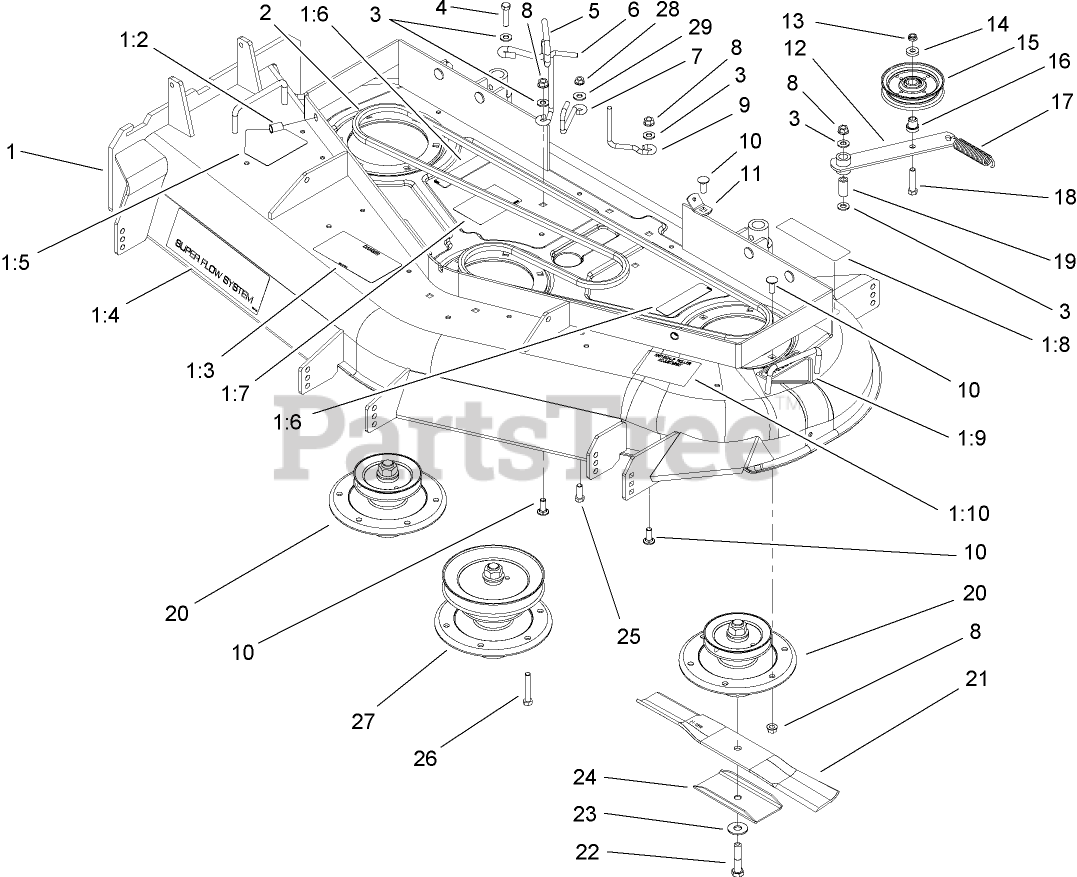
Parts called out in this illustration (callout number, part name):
1	DECK ASM
1:2	INSERT-NUT
1:3	DECAL-DANGER, THROWN OBJECT
1:5	DECAL-DANGER
1:6	DECAL-DANGER
1:7	DECAL-ROUTING, BELT
1:8	DECAL-TORQUE
1:9	DECAL-DANGER
1:10	DECAL-ANTI SCALP
2	V-BELT
3	WASHER-FLAT
4	SCREW-HH
5	GUIDE-BELT
6	GUIDE-BELT
7	GUIDE-BELT
8	NUT-HF
9	ROD-BELT
10	SCREW-CARR
11	PLATE-SPRING
12	IDLER ARM ASM
13	NUT-HEX
14	WASHER-FLAT
15	PULLEY-IDLER
16	BUSHING-PULLEY
17	SPRING-EXTENSION
18	SCREW-HH
19	SLEEVE
20	SPINDLE HOUSING ASM
21	BLADE-18 INCH
22	SCREW-BLADE
23	WASHER-FLAT
24	STIFFENER-BLADE
25	SCREW-HH
26	SCREW-HH
27	SPINDLE HOUSING ASM
28	NUT-HF
29	WASHER-FLAT
